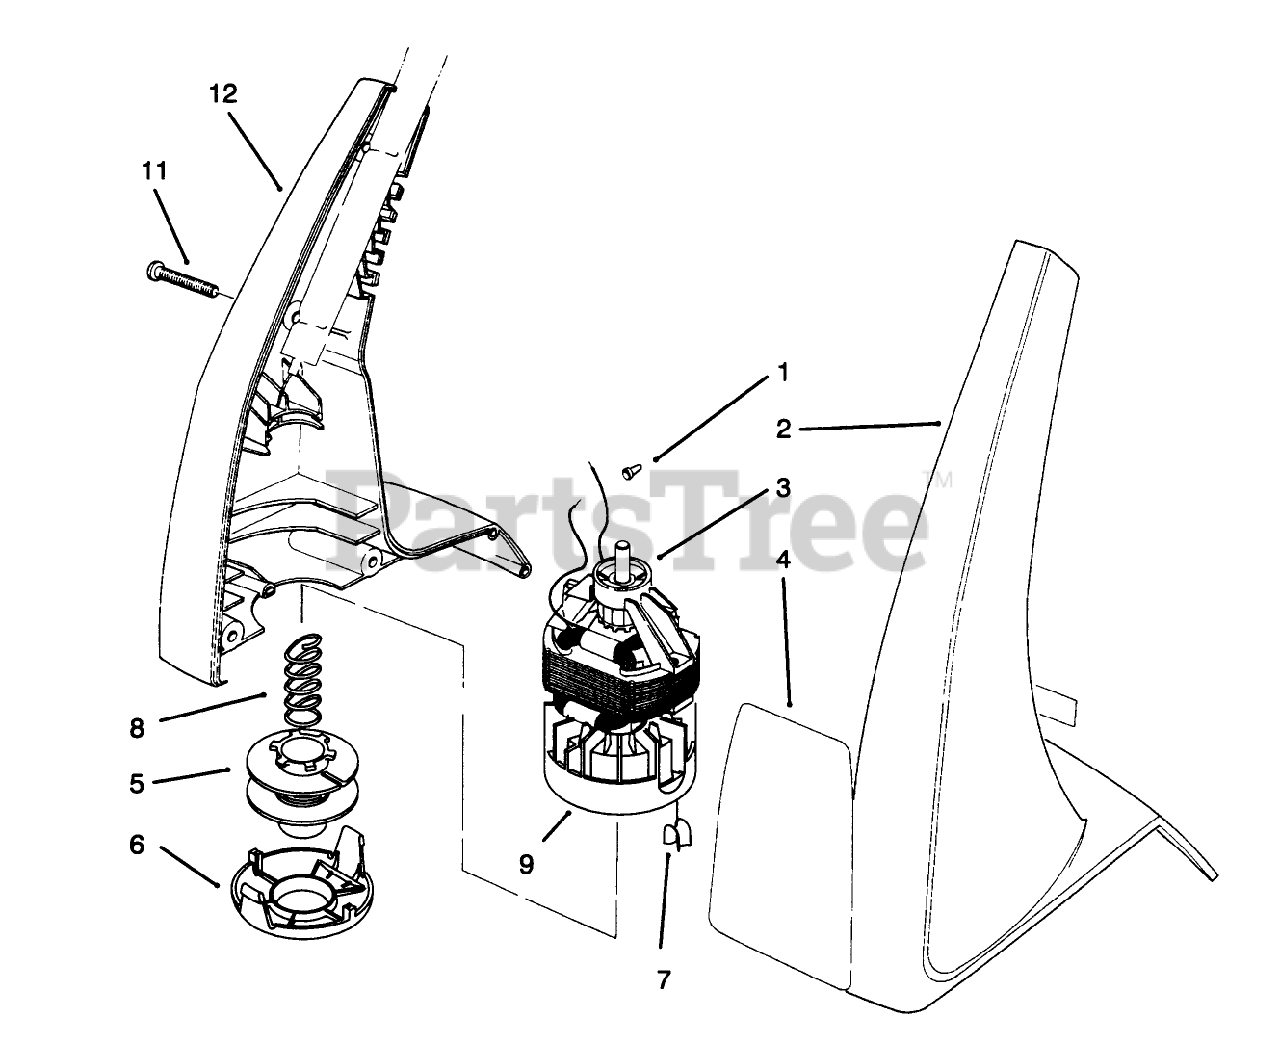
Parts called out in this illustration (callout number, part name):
1	CONNECTOR WIRE JOINT
2	HOUSING, 8", LH
3	Motor Assembly (Incl. Ref. #9 & 7 )
4	DECAL - 8" TRIMMER
5	20 Ft. .050 Dia. Cutting Line Prewound on Spool
6	CAP-SMALL
7	EYELET
8	SPRING-COMPRESSION
9	Drum
11	Screw
12	ASM-HOUSING,RH-SERVICE
